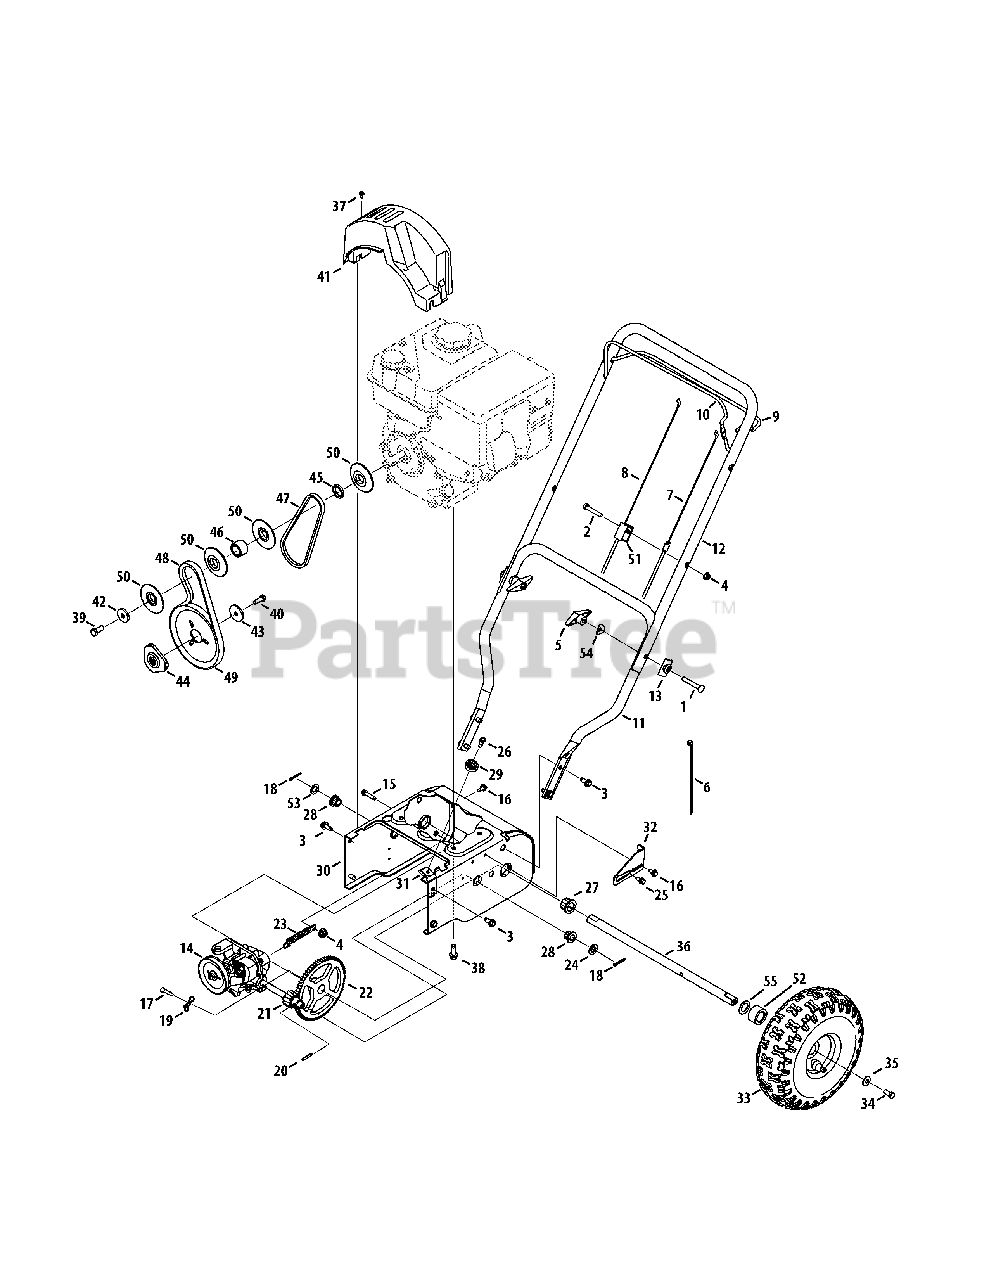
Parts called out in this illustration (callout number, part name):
1	Carriage Screw, 5/16-18 x 2.25
2	Mach. Screw, 1/4-20 x 1.50
3	Screw, 5/16-18 x .75
4	Flange Lock Nut, 1/4-20
5	Wing Knob, 5/16-18
6	Cable Tie
7	Drive Cable
8	Auger Cable
9	Drive Control
10	Auger Control
12	Upper Handle
13	Handle Tab
14	Transmission Assembly
15	Self-Tapping Screw, 1/4-20 x 1.25
16	Screw 1/4-20 x .625
17	Clevis Pin
18	Cotter Pin, 1/8 x 1.0
19	Bow Tie Cotter Pin, 72
20	Roll Pin
21	Pinion, 14T
22	Gear, 70T
23	Extension Spring
24	Flat Washer
25	Shoulder Screw, 1/4-20
26	Shoulder Screw, 1/4-28
27	Hex Flange Bearing
28	Hex Flange Bearing
29	Cable Roller
30	Drive Housing Frame
31	Auger Cable Bracket
33	Wheel Assy. ,Snow Hog, Gray
34	Lock Bolt, 5/16-24 x .75
35	Bell Washer, .34 x .872 x .06
37	Hex Screw, #10-16 x .500
38	Sems Screw, 3/8-16 x 1.0
39	Hex Bolt ,3/8-24 x .875
40	Lock Bolt, 5/16-24 x .875
41	Belt Cover
42	Flat Washer, .406 ID x 1.25 OD
43	Flat Washer, .34 ID x 1.50 OD
44	Pulley: Adapter ,.75 Dia.
45	Spacer, .876 x 1.25 x .19
46	Spacer, .876 x 1.25 x .86
47	V-belt, 3/8 x 21.108 Lg.
48	V-belt, 3/8 x 26.375 Lg.
49	Auger Pulley
50	Pulley Half
51	Cable Clip
53	Flat Washer, .53 x .93 x .05
54	Saddle Washer
55	Flat Washer, .793 x 1.24 x .06
